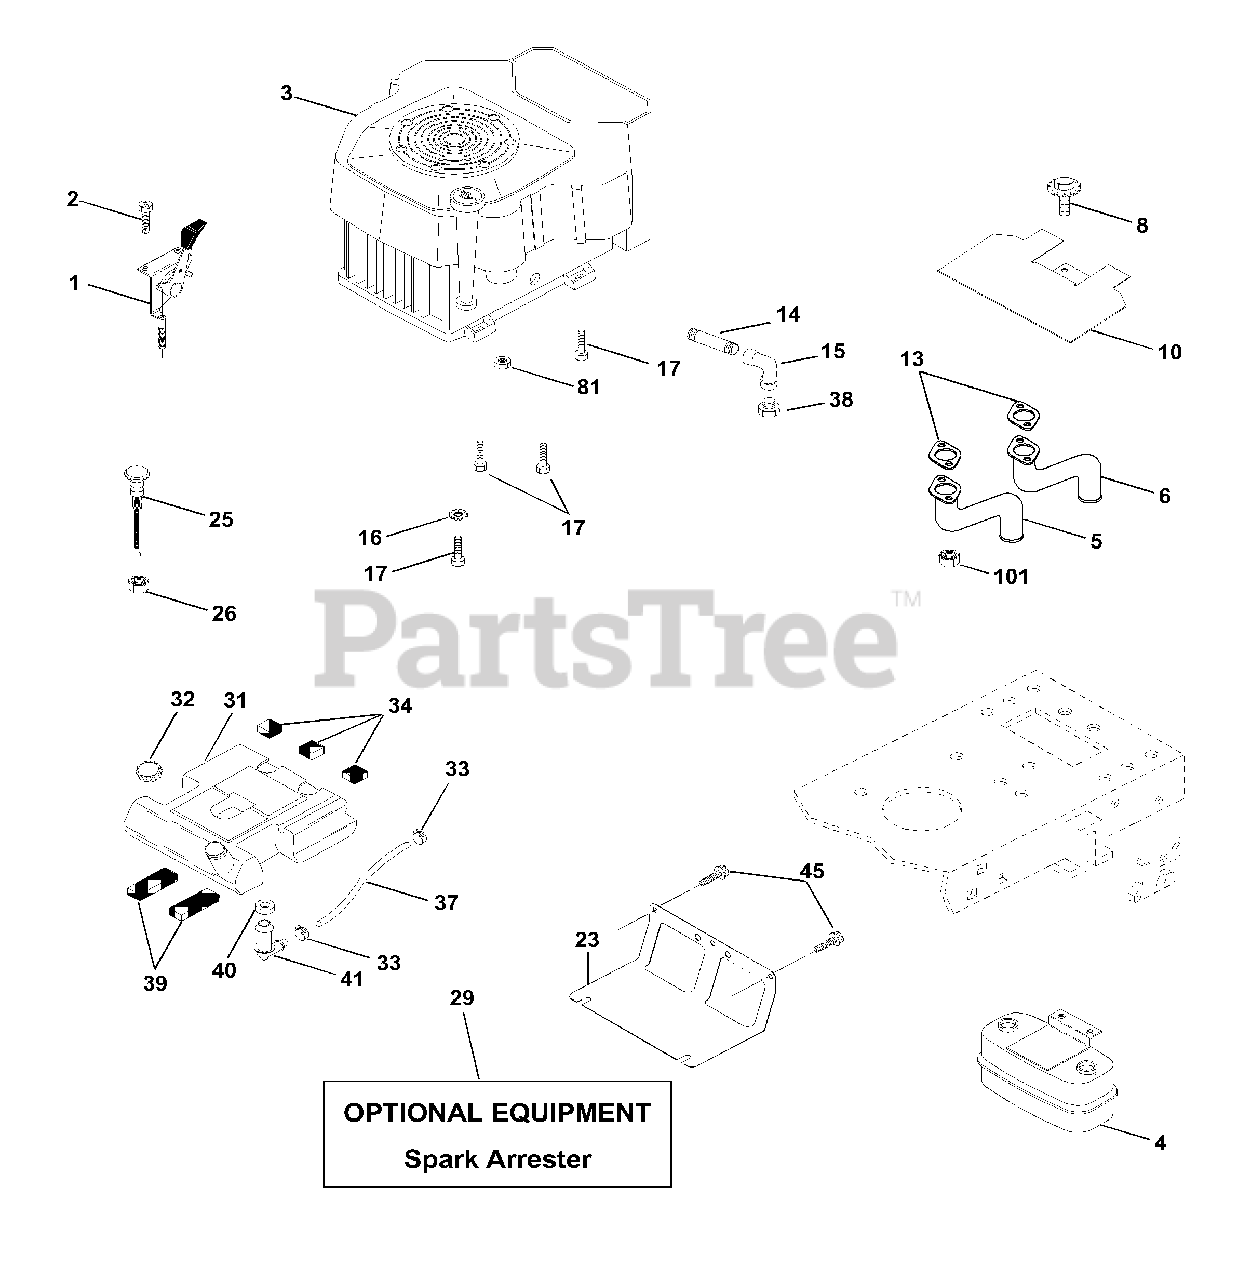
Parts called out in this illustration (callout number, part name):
1	Control, Throttle
2	Screw, Hex Head, Thread Cutting 1/4-20 x 5/8
5	Pipe Exhaust, LH
6	Pipe Exhaust, RH
8	Bolt 5/16-18 UNC x 3/4 w/Sems
10	Shield Heat Muffler
13	Muffler Gasket
14	Nipple, Pipe 3/8 NPT x 4-1/2
15	Elbow, Standard 90° 3/8-18 NPT
16	Washer, Lock, External Tooth 3/8
17	Screw Thdrol 3/8-16 x 1-1/2
23	Shield, Browning / Debris Guard
25	Choke Control
26	Nut, Keps 3/8-24 UNF
29	Kit, Spark Arrestor
31	Tank Fuel 3 50 Rear
32	Cap Asm Fuel W/sym Vented
33	Clamp, Hose
34	Pad, Spacer
37	Line, Fuel
38	Plug, Oil Drain
39	Pad, Idler
40	Bushing
41	Stem, Fuel Tank
45	Screw 3/8-16 x 3/4 Smgml Tap R
81	Nut, Flange 1/4-20 Starter Nut
101	Nut Flange M8-1.25 Non-Lk Zink
